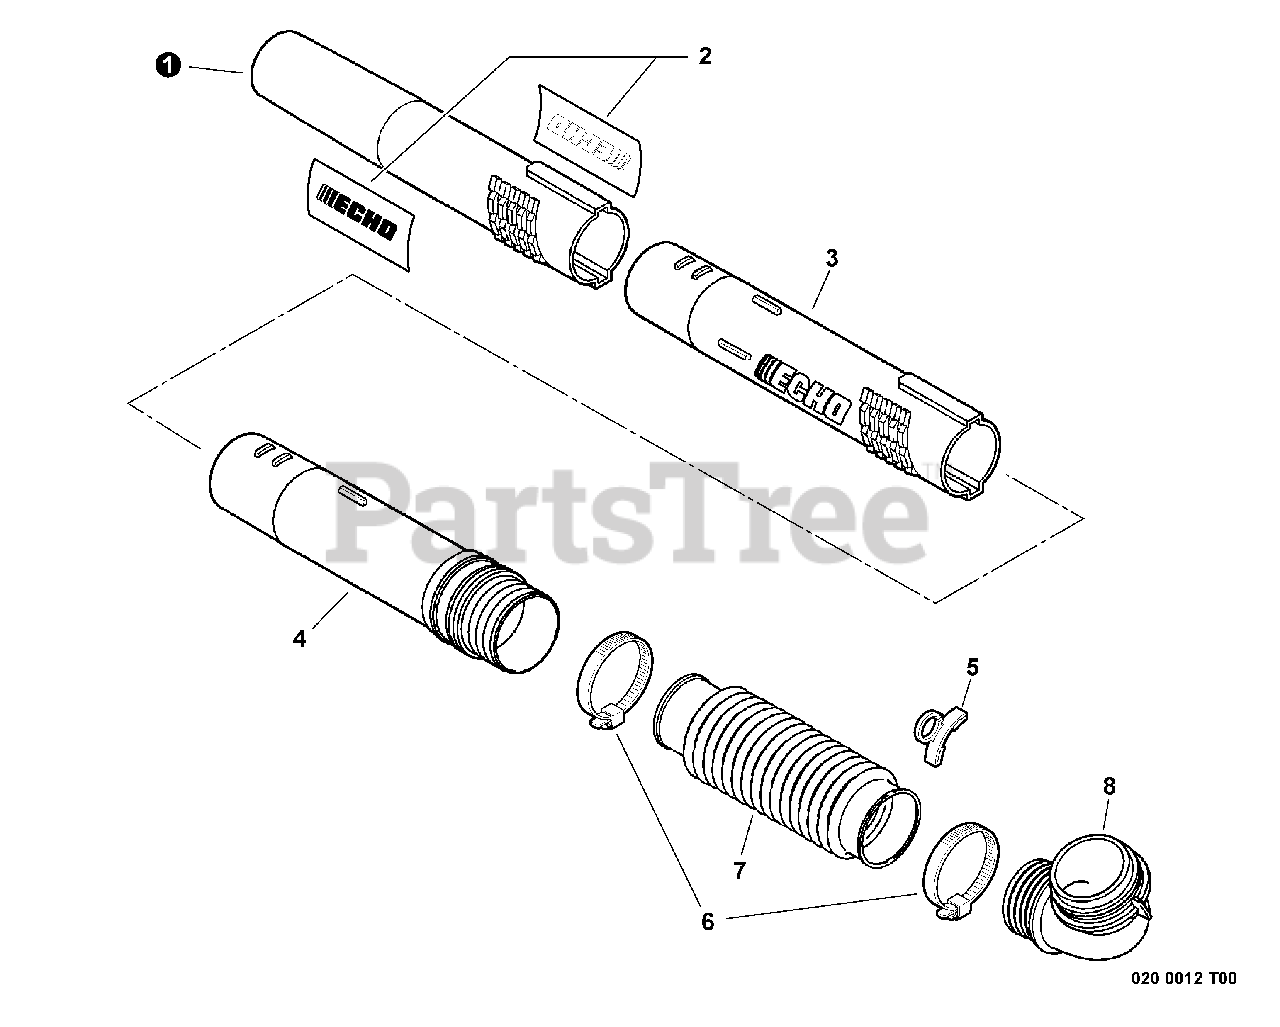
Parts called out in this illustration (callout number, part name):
1	TUBE, BLOWER - ROUND NOZZLE
2	LABEL, ECHO BLOWER TUBE
3	TUBE, BLOWER - STRAIGHT
4	TUBE, BLOWER - SWIVEL
5	CLIP, CABLE
6	CLAMP 58.7 MM / 82.5 MM
7	TUBE, BLOWER - FLEXIBLE
8	TUBE, BLOWER - ELBOW
